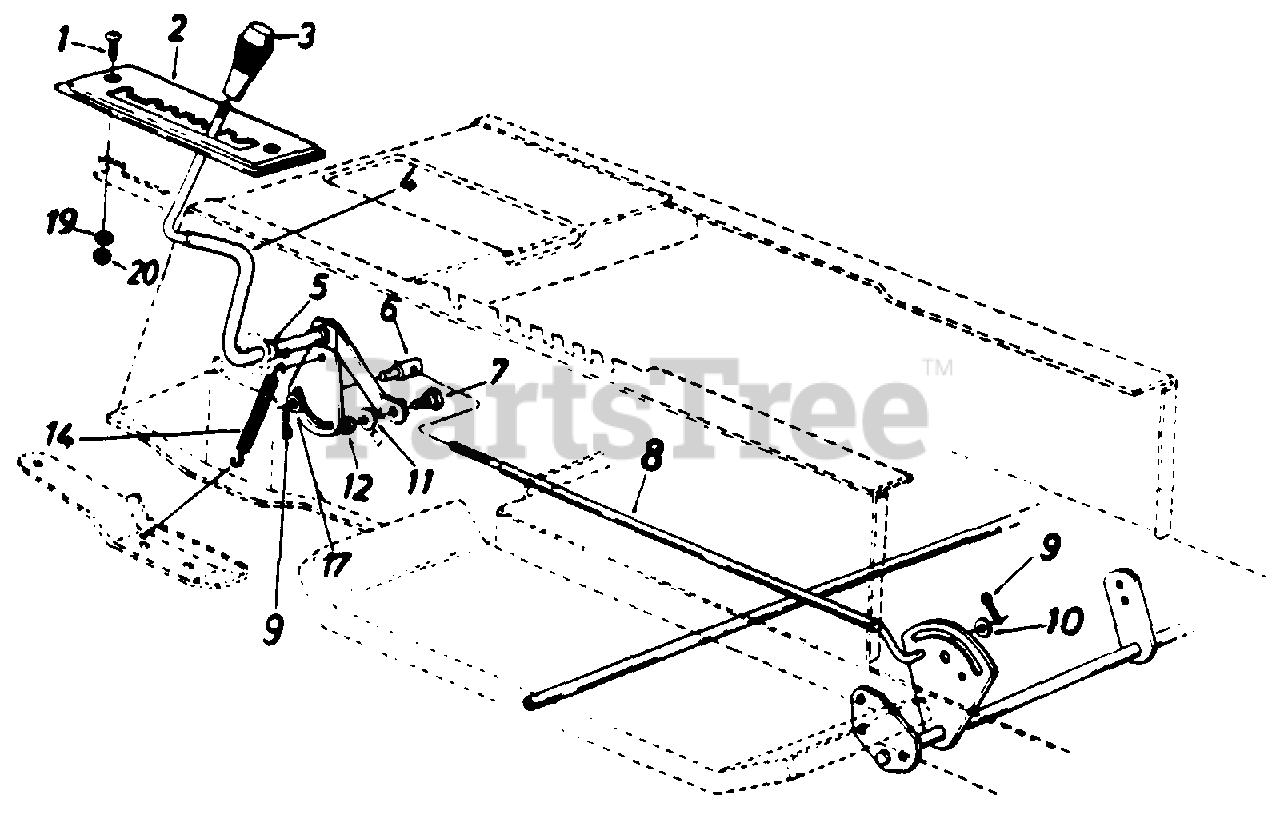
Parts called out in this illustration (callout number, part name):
1	Truss Mach. Scr. 1/4-20 x .75" Lg.
4	Speed Selector Lever Ass'y.
5	Flat Washer .53" I.D. x .93"
6	Ferrule 3/8-24 x .37" Dia.
7	Shoulder Bolt
8	Speed Control Link
9	Cotter Pin 3/32" Dia. x 1.0"
10	Fl-Wash. .469" I.D. x .88"
11	L-Wash. 5/16" I.D.
12	Hex Nut 5/16-18 Thd.
14	Spring .38" O.D. x 3.18" Lg.
17	Fl-Wash. .385" I.D. x .62"
19	L-Wash. 1/4" I.D.
20	Hex Nut 1/4-20 Thd.
